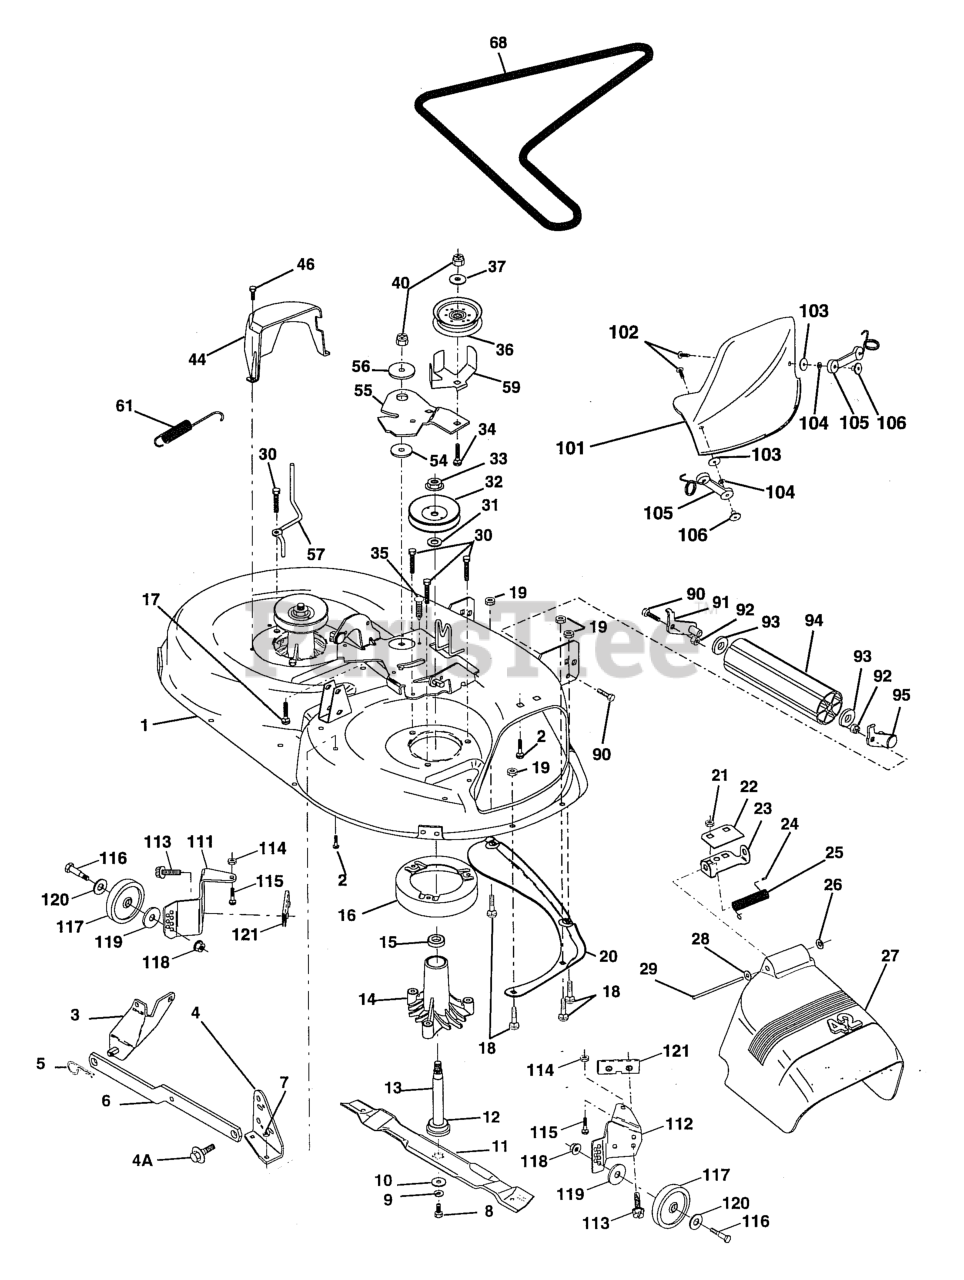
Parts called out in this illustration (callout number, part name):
1	DECK ASM MWR 42"
2	RP BOLT 5/16-18 X3/4 ZN/YEL GR
3	BRKT ASM SWAY BAR
4	BRKT DECK SW BAR
4A	BOLT SHD 5/16-18
5	RETAINER-SPRNG RB
6	REAR SUSP ARM
7	NUT.71038.31-18.HEX.NYLOCK
8	BLADE BOLT
9	LOCKWASHER
10	WASHER.BLADE
11	BLADE.42".MULCH
12	BEARING.BALL.#6204.(MANDREL)
13	SHAFT ASM VENT
14	HOUSING.MANDREL.VENTED (MACHD)
16	STRIPPER
17	BOLT
18	BOLT
19	NUT.71038.31-18.HEX.NYLOCK
20	BAFFLE
21	NUT.71038.31-18.HEX.NYLOCK
22	STIFFENER BRACKET
23	DEFLECTOR BRACKET
24	CAP-SLEEVE LT
25	SPRING TORSION
26	NUT PUSH M
27	SHIELD.DEFLECTOR.MOWER.42".BLK
28	Washer 11/32 X 5/8 X 16 Ga
29	ROD.HINGE
30	SCREW
31	WASHER
32	MANDREL PULLEY
33	NUT
35	FASTENER.XMAS.TREE
36	FLAT IDLER PULLEY
37	WASHER
40	NUT
44	GUARD MANDREL LH BLACK
46	SCREW.1/4-20X5/8
54	HARDENED WASHER
55	IDLER ARM
56	SPACER RETAINER
59	GUARD, BELT
61	SPRING EXTENSION
68	RP.V-BELT
90	BOLT
91	BRACKET LH (A)
93	Washer 17/32 X 7/8 X 16 Ga
94	NOSE ROLLER
95	BRACKET RH (B)
101	COVER MULCH 42"
102	SCREW
103	LOCKWASHER #10
105	LATCH ASSEMBLY
106	WELDNUT
111	BRACKET
112	BRACKET
113	BOLT
114	NUT
115	BOLT.CARR.5/16-18X1/2
116	FENDER
117	WHEEL.GAUGE.BLK.4.93
118	LOCKNUT
119	WASHER.5/16.FLAT.STE.STD.
120	Washer 17/32 x 15/16 x 12 Ga.
121	BRACKET.EXTRUDED.GAGE.WHEEL
